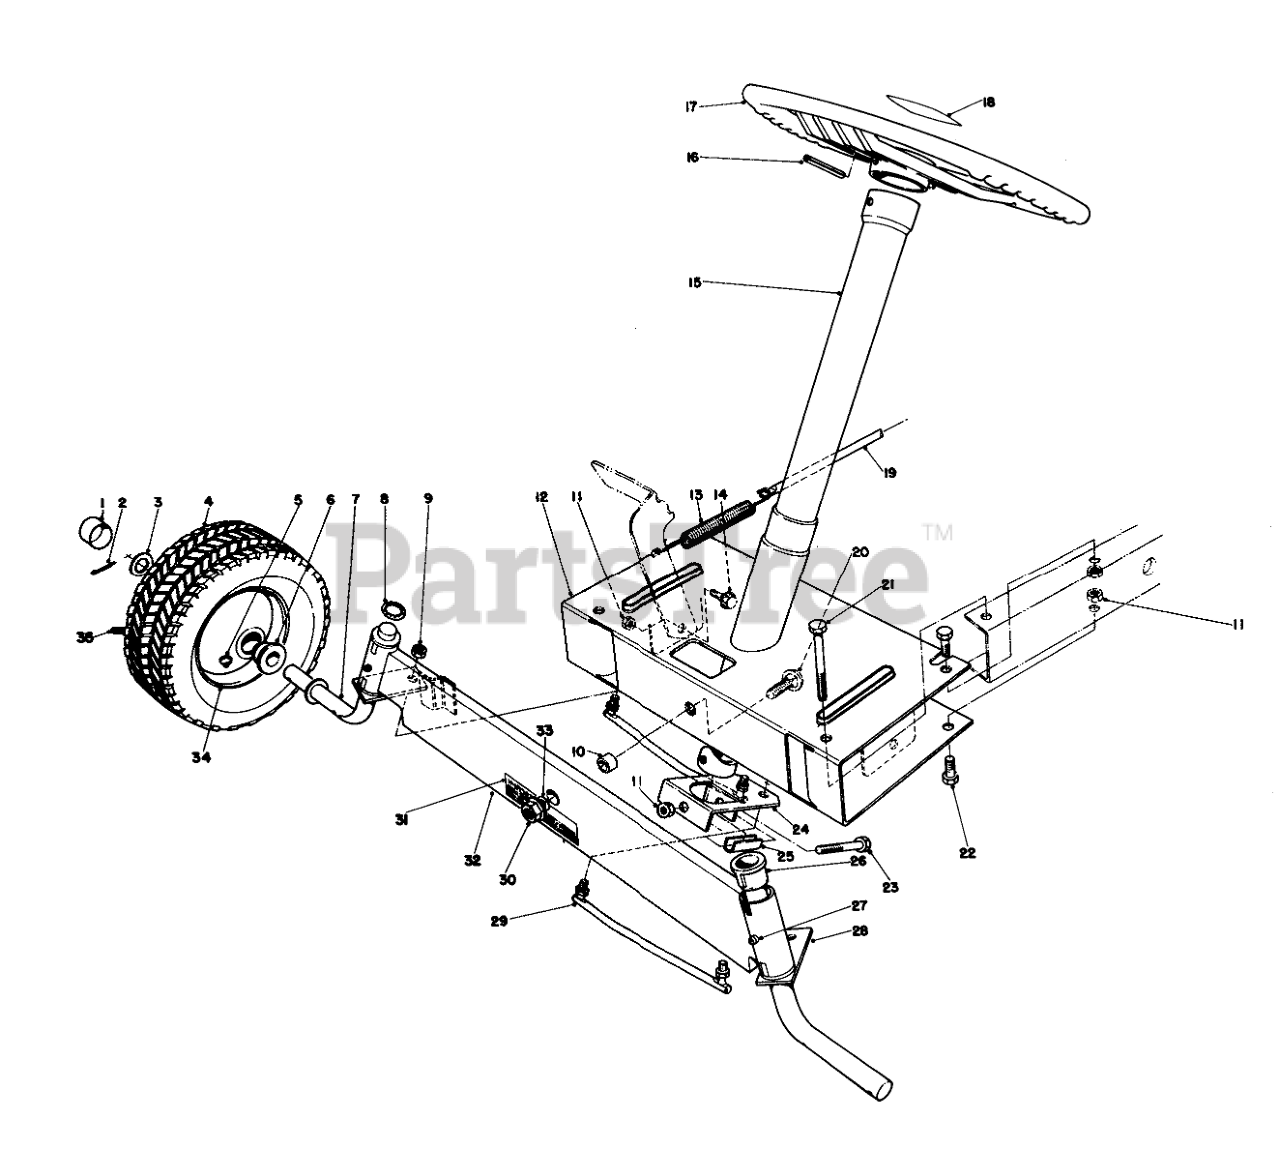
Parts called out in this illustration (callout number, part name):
1	Hub Cap
2	PIN-COTTER
3	WASHER-FLAT
4	Tire Turf King
5	FITTING-GREASE
6	BUSHING
7	SPINDLE WA RH
8	RING-RETAINING
9	NUT-LOCK NI
10	FRONT AXLE SPACER
11	NUT-LOCK, CONE
12	Front Frame
13	BRAKE TENSION SPRG O
14	SCREW-SHOULDER
15	Steering Tube
16	PIN-ROLL
17	Steering Wheel
18	Decal
19	Brake Rod
20	SCREW-CARR
21	SCREW-HH
22	SCREW-HH
23	SCREW-HH
24	Lever Steering
25	Spacer-Steering Tube
26	BUSHING
27	GREASE FITTING
28	Spindle L.H.
29	TIE ROD ASM
30	NUT-HF
31	Decal-Warning
32	Front Axle
33	WASHER-THRUST
35	STEM-VALVE
